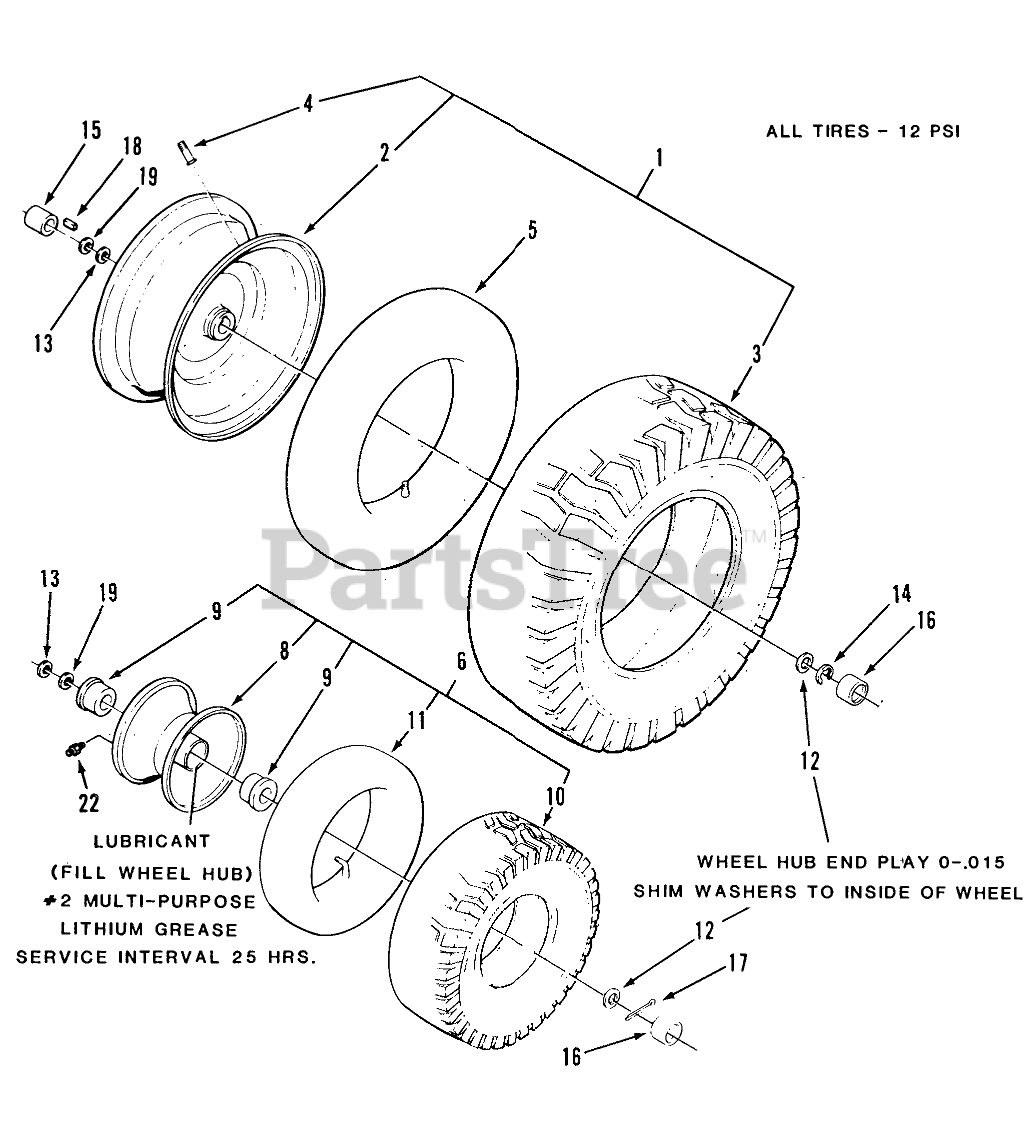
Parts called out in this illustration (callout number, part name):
1	ASSY WHEEL & TIRE
2	ASSY WHEEL
3	TIRE TURF SAVER 16X6.50-8
4	VALVE
5	TUBE-INNER
6	ASSY-WHEEL & TIRE
8	ASS'Y-WHEEL
9	BUSHING
10	Tire-Front 4-10 X 3.50-4
12	WASHER-FLAT
13	WASHER
14	E Ring
15	LH AXLE SPACER
16	HUB CAP-FLAT BLACK
17	Cotter Pin
18	SQ KEY
19	WASHER-SHIM
